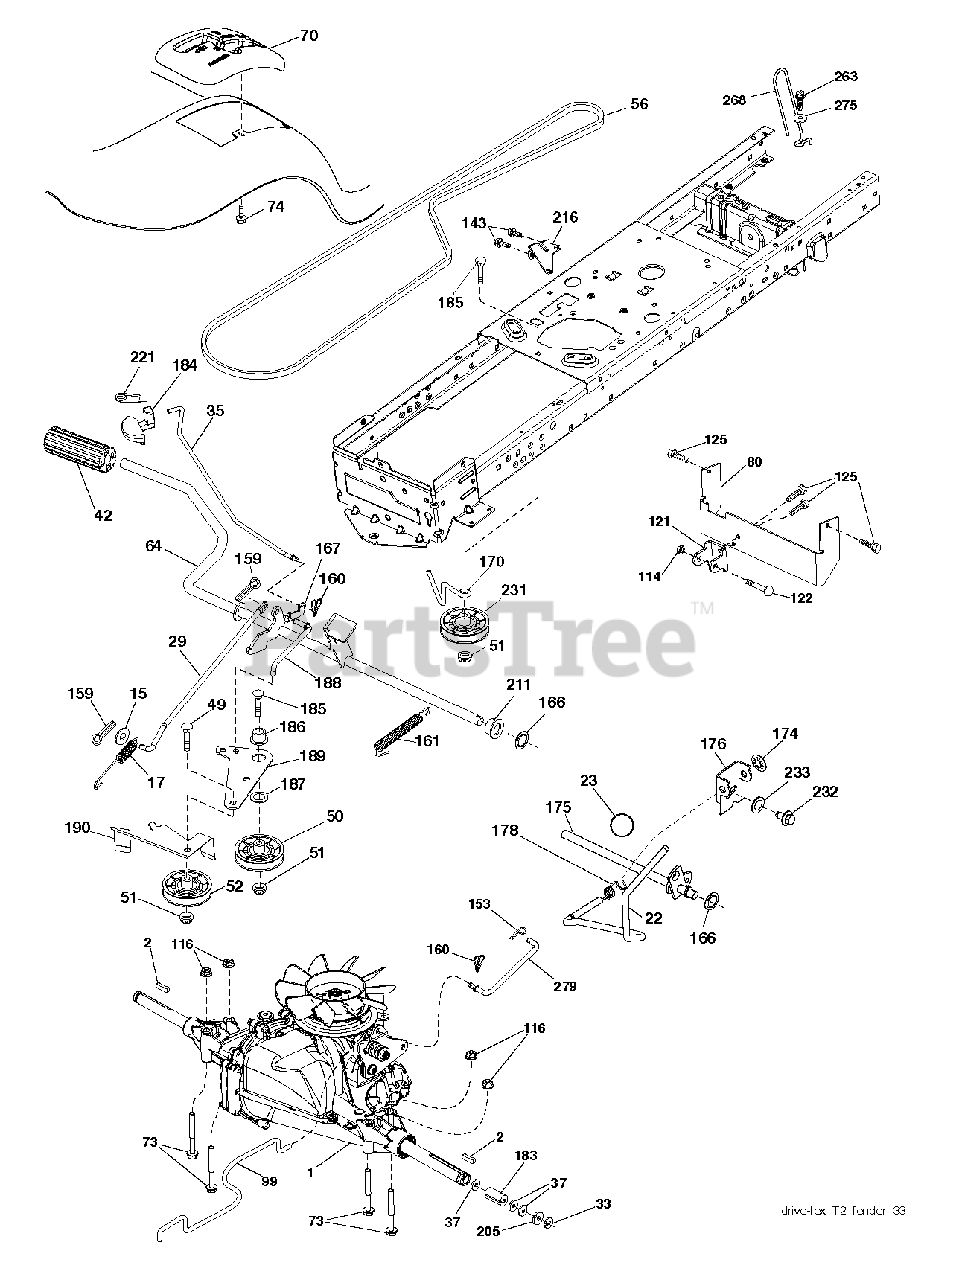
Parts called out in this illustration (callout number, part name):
2	SQUARE KEY
17	SPRING.BRAKE.HG3000/3500
22	ROD.SHIFT.FENDER.TLT.2006
23	KNOB.DUCKHEAD.1/2
29	ROD.BRAKE.T2.TEX
33	E-RING LT
35	ROD, BRAKE, PARK
42	PEDAL COVER T
49	BOLT
50	IDLER.FLAT.910.OFFSET
51	NUT LOCK FLG 3/8-16 UNC
52	IDLER.V-GROOVE.910.OFFSET
56	Ground Drive Belt, T2 HP CE
64	SHAFT.ASM.PEDAL.BRAKE.
70	CONSOLE.SHIFT.STL.HYD.BLACK
73	BOLT HEX 5/16-18 GR 5
74	SCREW.HI-LO.CONSOLE
80	Strap.Torque.T2
99	ROD.ASM.BYPASS.SPRING.T2.FS
114	NUT.71038.31-18.HEX.NYLOCK
116	NUT LOCK HEX FLANGE 5/16-18
121	BRACKET STRAP TORQUE
122	BOLT.5/16-18X2.5
125	SCREW
153	RETAINER M
159	COTTER PIN
160	RETAINER CLIP
161	SPRING, RETURN LT
166	NUT.PUSH.625
167	LATCH.BRAKE.SPRING
170	KEEPER.CENTER SPAN.1.688
174	NUT.PUSH.500.2006
175	SHAFT.ASM.SHFT.T2.TLT
176	ARM.CLEVIS.ROD.SHIFT
178	SPRING.SHIFT.GT2006
183	SPACER, AXLE PVST
184	HANDLE.PARKING.BRK.PRED.LT.RED
186	SPACER.RETAINER
187	WASHER 12/32X2X10GA
188	LINK.CLUTCH.GROUND.DRIVE
189	BELLCRANK.GROUND.DRIVE.TEX.
190	KEEPER.BELLCRANK.DRIVE
211	BUSHING.SHAFT.BRAKE.HAND
216	BRACKET.PULLEY.IDLER.W/TEX
221	RETAINER.SPRING.CLIP.H
231	IDLER.V-GROOVE.1.688.OFFSET
232	BOLT FIN HEX 7/16-14 X 1
233	WASHER SERRATED
263	SCREW, 3/8-16X3/4
275	WASHER
279	LINK.SHIFT.T2
